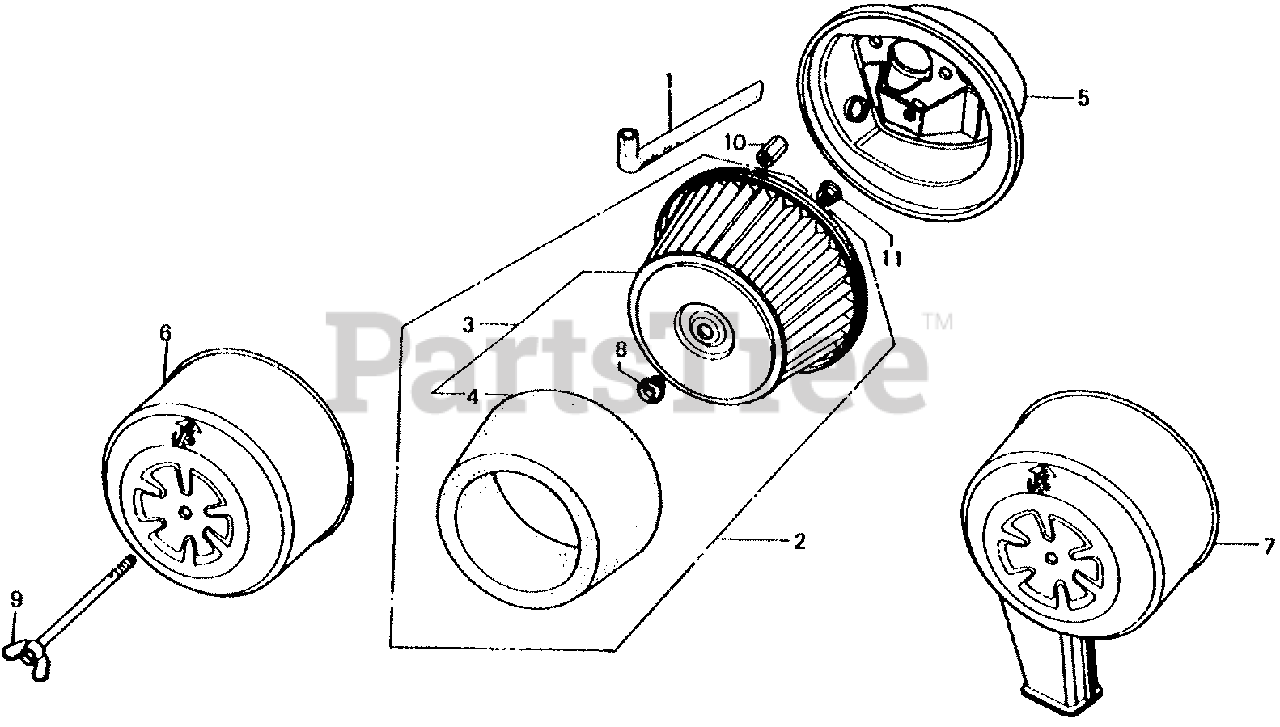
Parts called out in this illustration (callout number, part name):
2	ELEMENT, AIR CLEANER
3	ELEMENT, AIR CLEANER
4	ELEMENT B, AIR CLEANER
